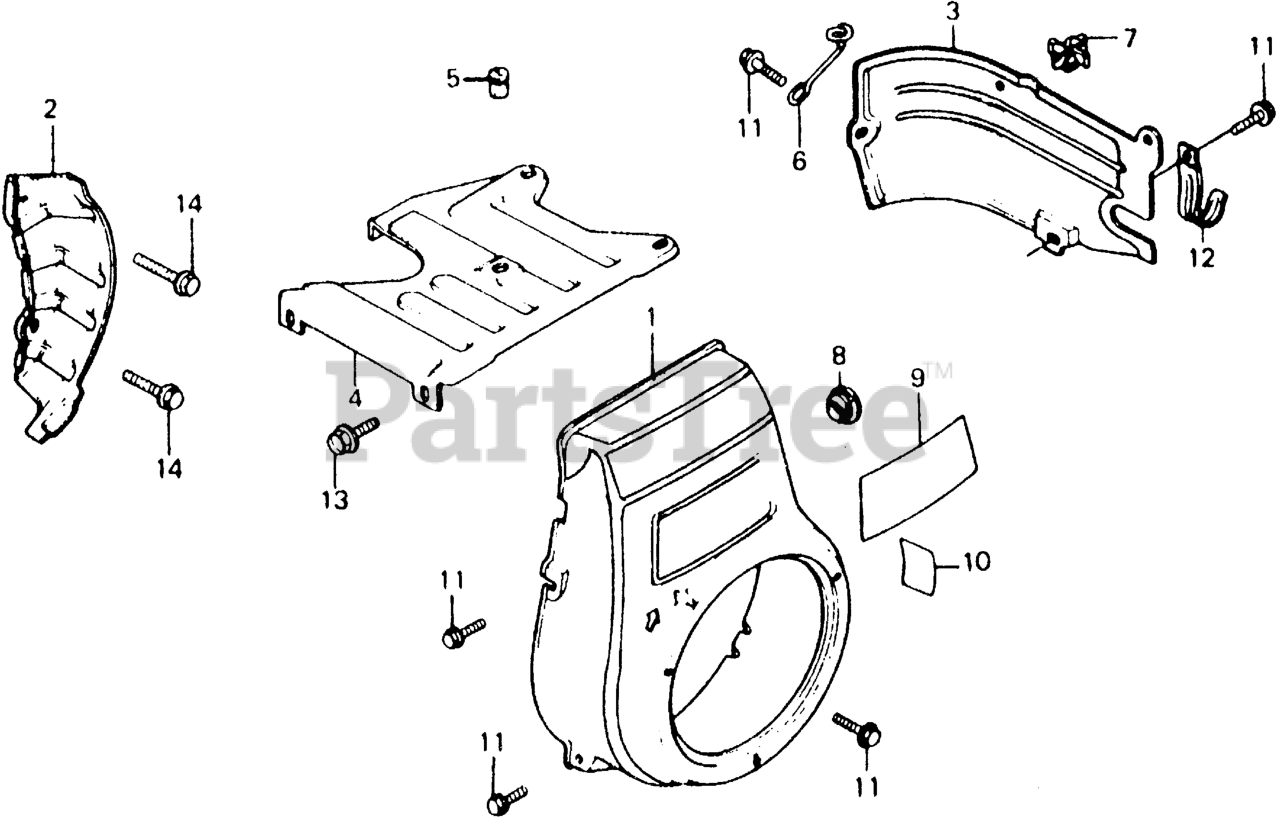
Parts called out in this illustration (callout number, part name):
1	COVER, FAN *R280* (POWER RED)
2	PLATE, SIDE
3	SHROUD
4	COVER, TOP
5	GROMMET, TOP COVER
6	CLAMP, IGNITION TUBE
7	CLIP, IGNITION WIRE (8MM)
8	GROMMET, DRAIN HOLE
9	EMBLEM, GENERAL EXPORT
10	MARK, OIL CAUTION
11	BOLT, FLANGE (6X12) (CT200)
12	CLIP, WIRE HARNESS
13	BOLT, FLANGE (8X16)
14	BOLT, FLANGE (8X20)
